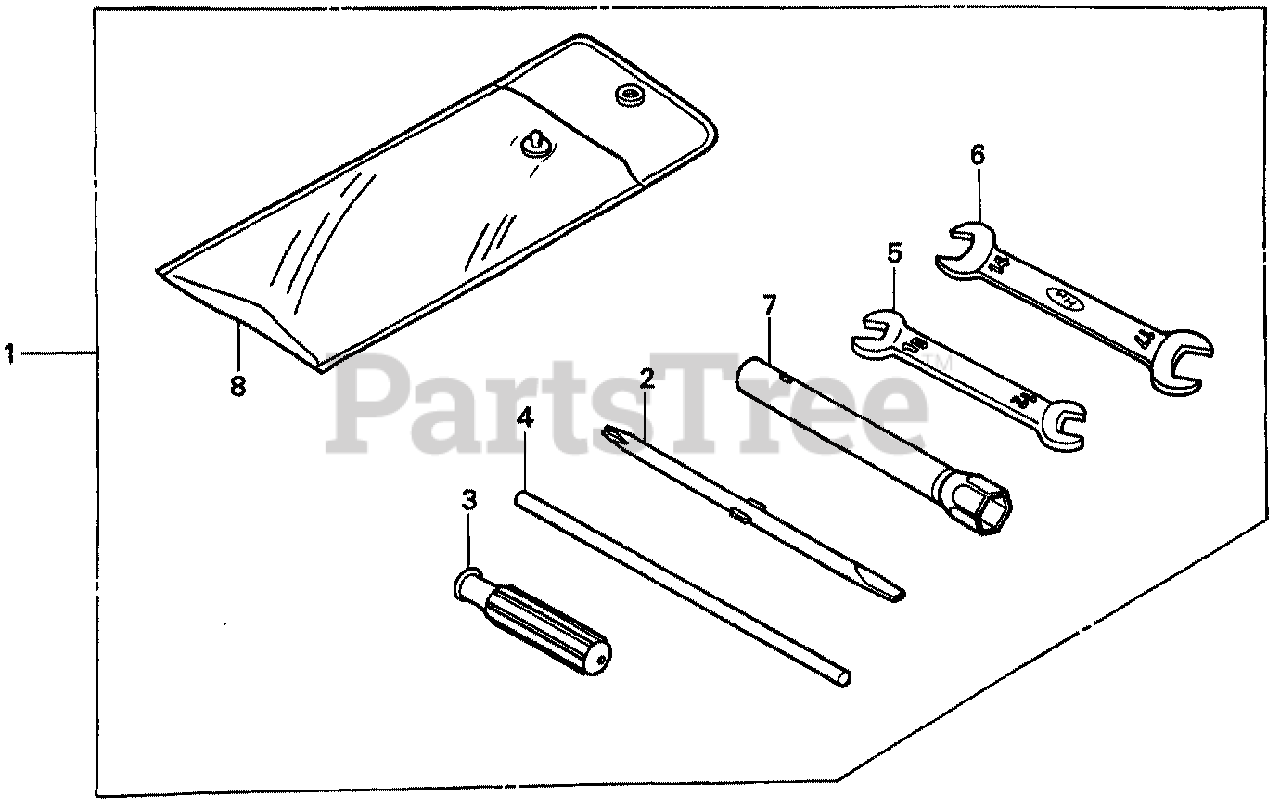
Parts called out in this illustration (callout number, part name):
2	SCREWDRIVER (NO.2 PHILLIPS -)
4	HANDLE, BOX WRENCH
5	SPANNER (10X12)
6	SPANNER (14X17)
7	WRENCH, BOX (P21)
